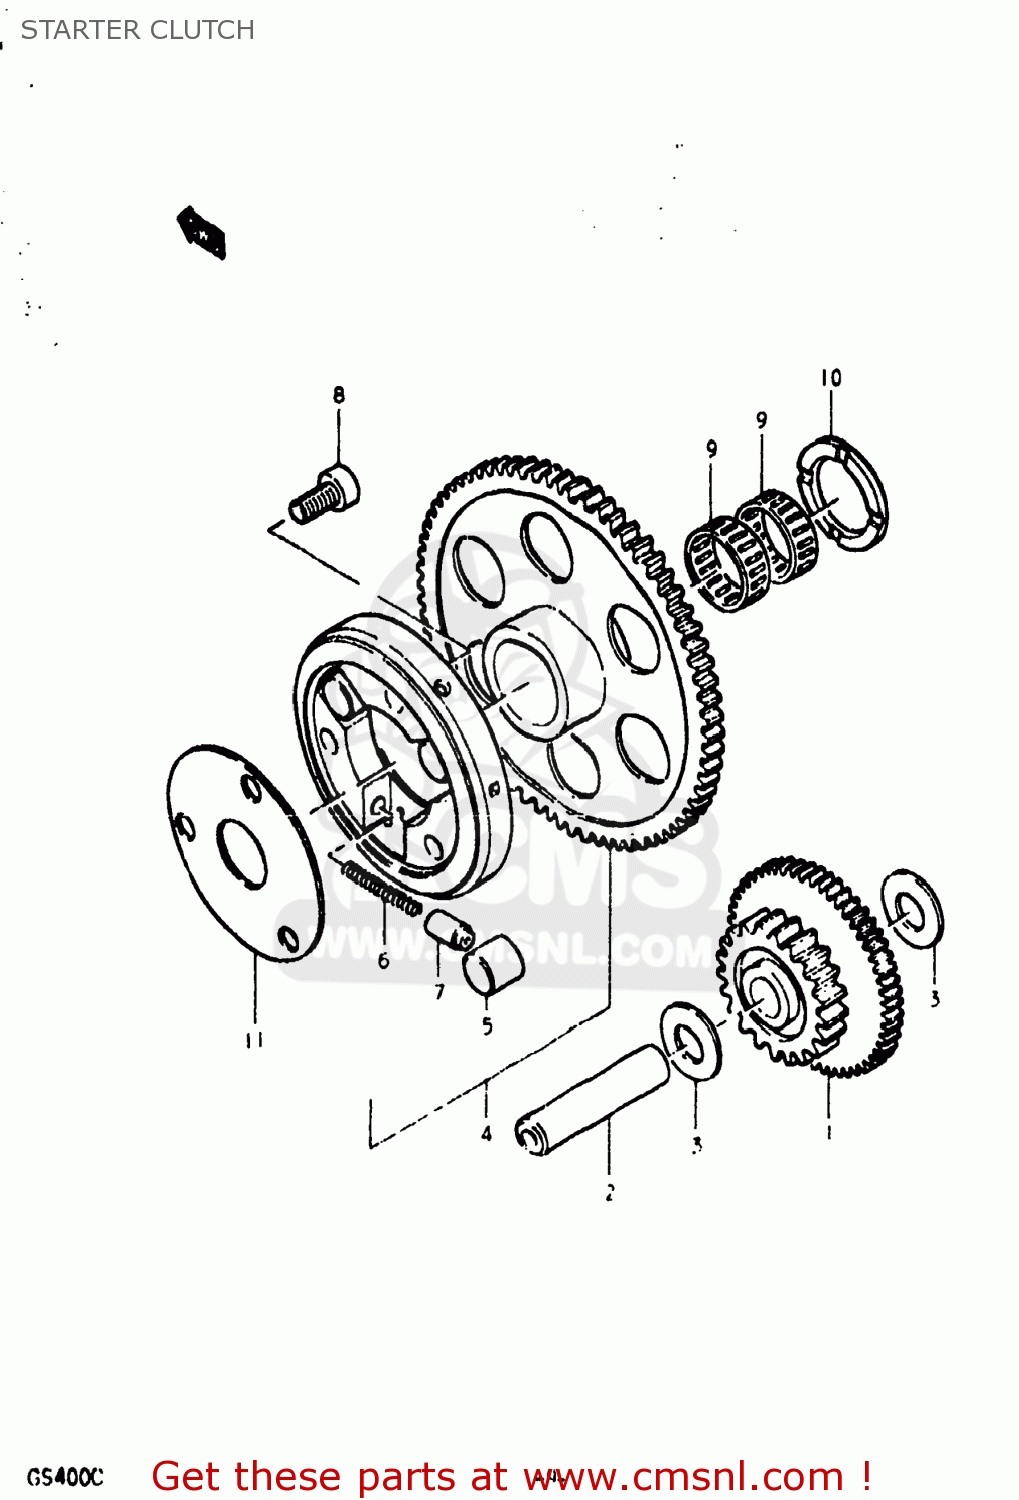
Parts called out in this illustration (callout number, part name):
1	GEAR,STARTER IDLER
2	PIN(7.4X13X56)
3	WASHER(13.3X25X0.85)
4	CLUTCH SET,STARTER
5	ROLLER(15X13)
6	SPRING
7	PIECE,PUSH
8	BOLT
9	BEARING(25X29X9.9)
10	WASHER(25X38X2.5)
11	SHIM,STARTER CLUTCH HUB
